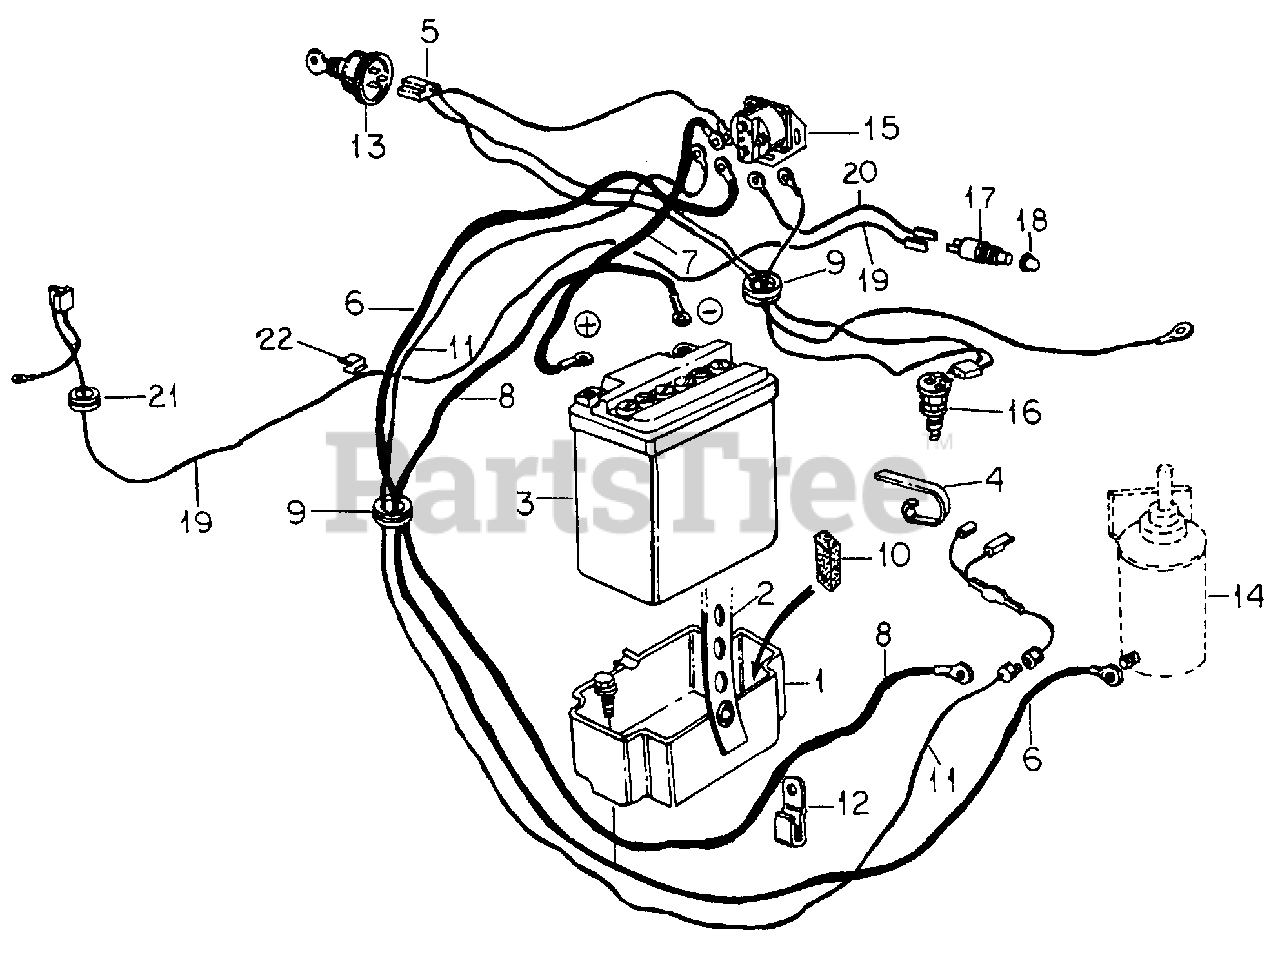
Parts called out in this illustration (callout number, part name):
1	Box, Battery
2	Strap, Battery
3	Battery
4	Spring, Neutral Start
5	Harness Assy, Cable
6	Cable Assy, Magneto Switch to Starter
7	Cable Assy, Battery to Magnetic Switch
8	Cable Assy, Battery to Ground
10	Strip, Foam
11	Cable Assy, Alternator to Magneto Switch
12	Clip, Cable Harness
13	Switch, Magneto Ignition & Starting
14	Motor Assy, Starter
15	Switch, Magnetic
16	Switch Assy, Neutral Starting
17	Switch, IPTO Neutral Starting
18	Boot, Neutral Start Switch
19	Harness, Seat Switch Cable
20	Cable, Neutral Starting Switch to Mag
21	Grommet, 5/16 x 23/32 x 7/16 D/C Rub
22	Clip, Safety Starting
